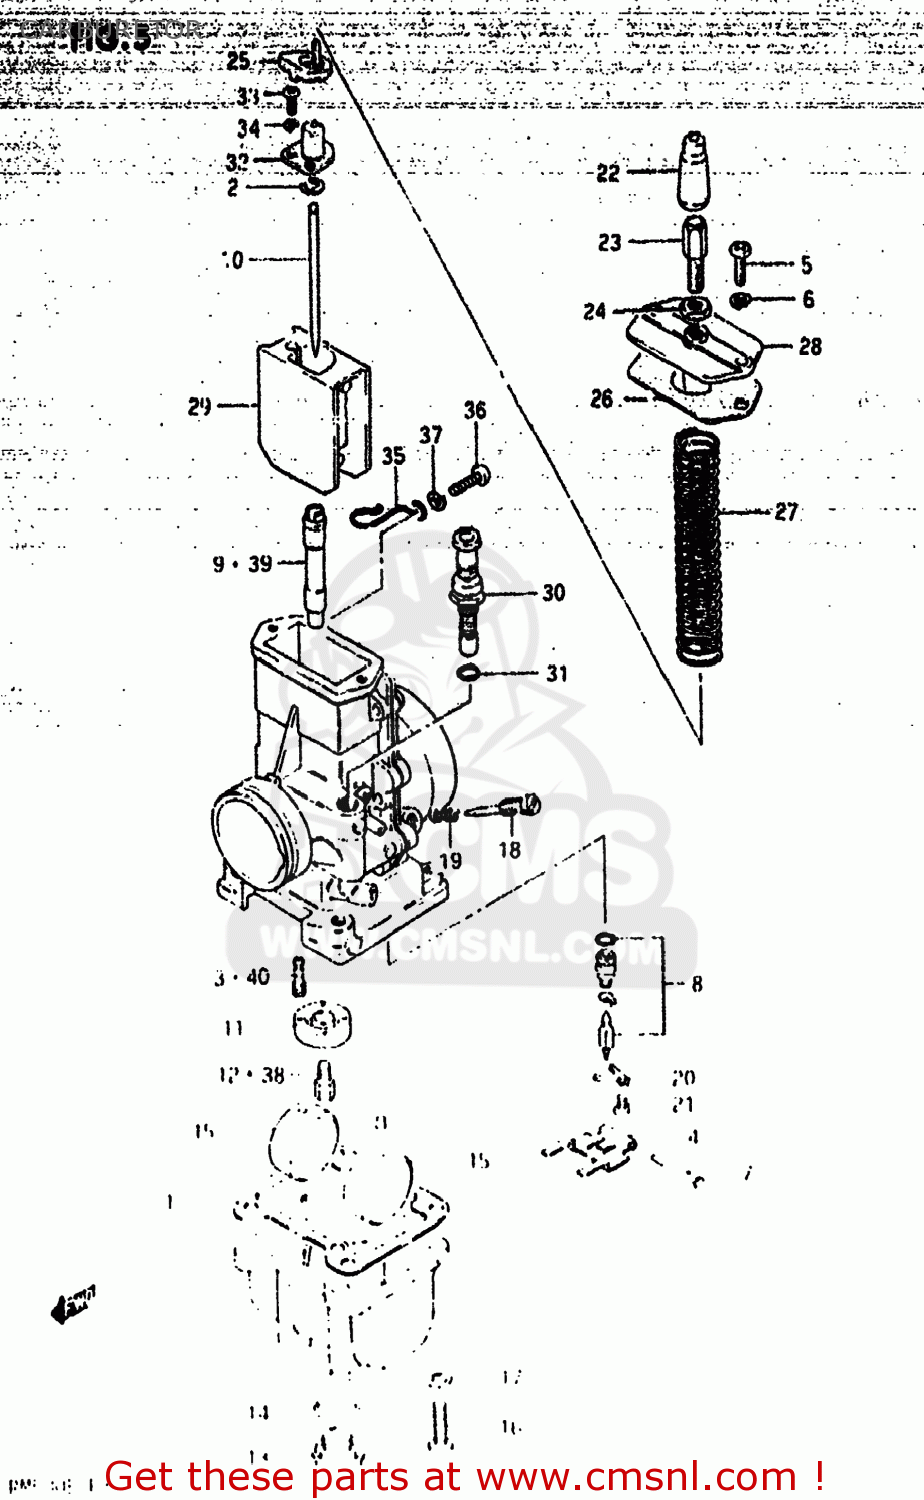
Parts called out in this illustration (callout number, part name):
0	CARBURETOR ASSEMBLY
1	GASKET,FLOAT CAHMBER (NAS)
2	CLIP
3	JET,PILOT(50)
4	ARM,FLOAT
5	SCREW
6	LOCK WASHER
7	PIN,FLOAT
8	VALVE ASSEMBLY,NEEDLE
9	JET,NEEDLE
10	NEEDLE JET
11	RING,MAIN JET FIXING
12	JET,MAIN(300)
13	SCREW,GUIDE
14	O RING,DRAIN PLUG
15	FLOAT
16	SCREW 5X20
17	LOCK WASHER
18	SCREW,PILOT AIR
19	SPRING
20	PLATE
21	SCREW 4X6
22	CAP,CABLE ADJUSTER
23	ADJUSTER,CABLE
24	NUT
25	SEAT,RETURN SPRING
26	GASKET,MIXING CHAMBER (NAS)
27	SPRING,THROTTLE VALVE
28	CAP,CARBURETOR,TOP
29	VALVE,THROTTLE
30	VALVE,STARTER
31	O-RING
32	PLATE,NEEDLE JET
33	SCREW
34	LOCK WASHER
35	CLIP
36	SCREW
37	LOCK WASHER
38	JET
39	JET,NEEDLE
40	JET
